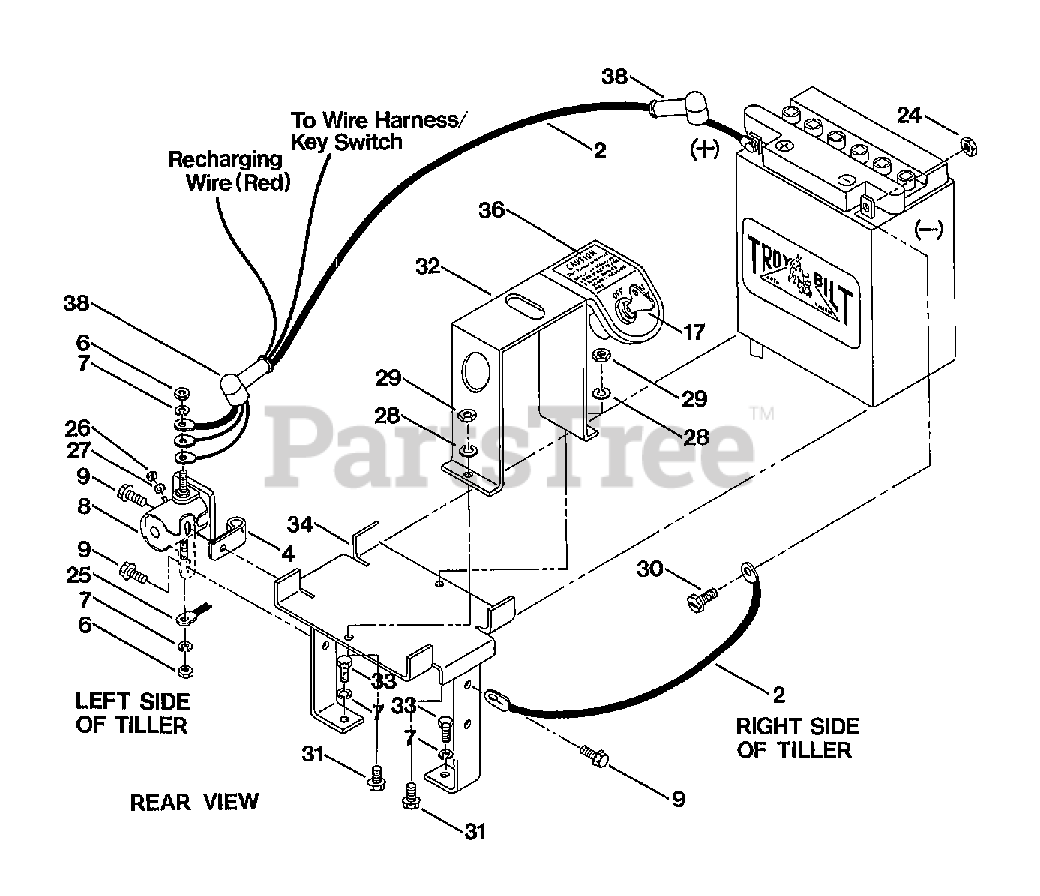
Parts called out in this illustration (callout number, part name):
2	CABLE- battery
4	CLIP- vent tube shield (small)
6	NUT- hex, 5/16"-24
7	LOCKWASHER-5/16"
8	SOLENOID-
9	SCREW-flanged hex head, self-threading 1/4"-20 x 1/2"
17	KEY- ignition
24	NUT-cable to battery, metric size 6mm -1mm pitch tap, orig. equipment-not avail. from Garden Way
25	CABLE-solenoid to starter
26	NUT- hex, #10-32
27	LOCKWASHER-external tooth, #10
28	LOCKWASHER-1/4"
29	NUT- hex head, 1/4"-20
30	BOLT-hex head/philips head combination, metric size 6mm-1mm pitch x 12mm Ig. orig. equipment-not avail. from Garden Way
31	BOLT- round head, square neck 1/4"-20 x 1 1/4"
32	BATTERY HOLD-DOWN CLAMP-with attached Key Switch Plate
33	BOLT- hex head, 5/16"-18 x 1"
34	BATTERY BRACKET
36	DECAL-key switch Instructions
38	RUBBER BOOT-terminal Insulating
